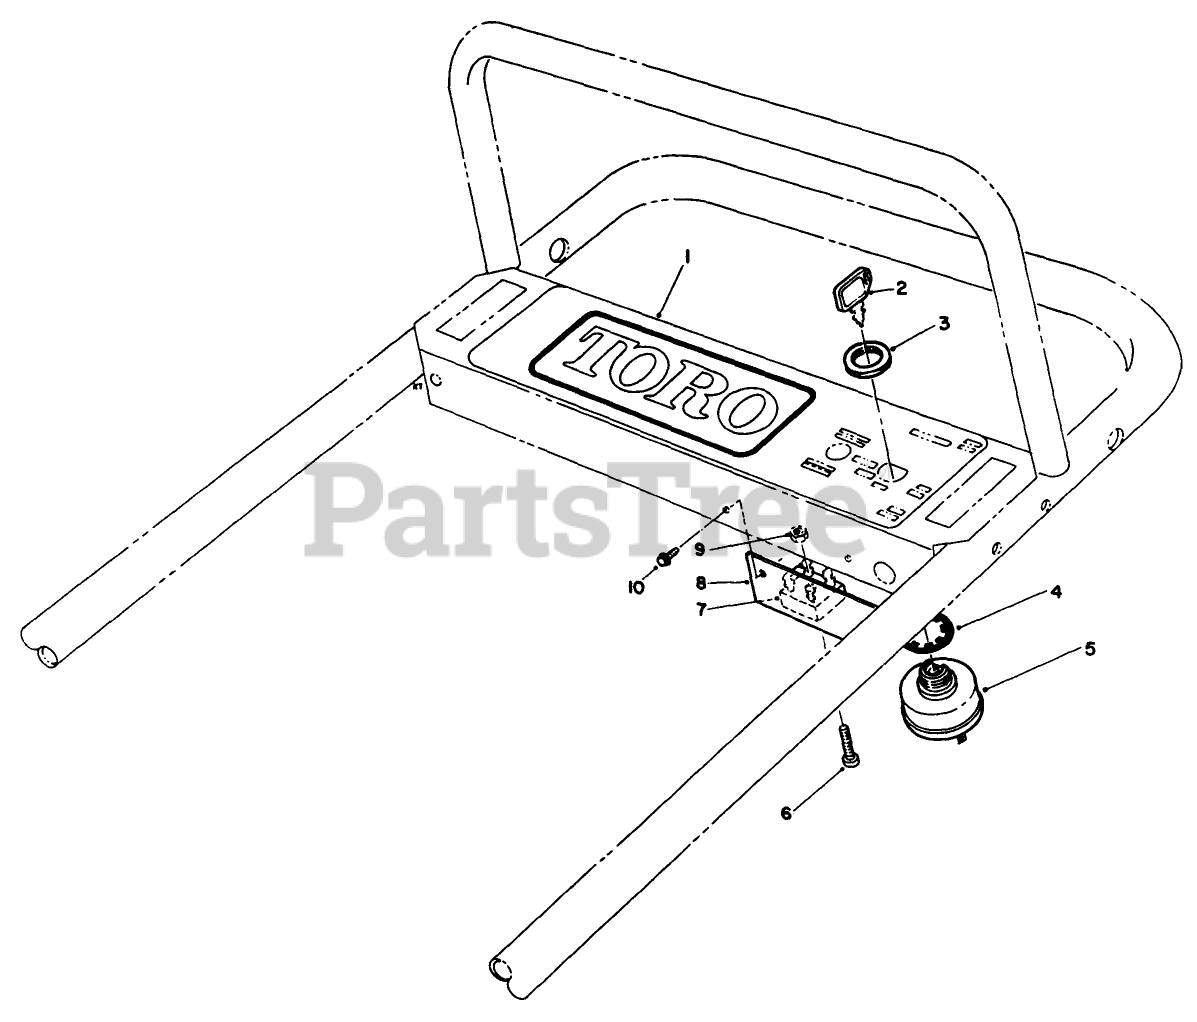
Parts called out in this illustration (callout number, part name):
1	Decal-Electric Start Panel
2	KEY-IGNITION
3	NUT-HH
4	WASHER-TOOTH, INTERNAL
5	Ignition Switch (Incl. Ref. #2-4)
6	SCREW-HWH
7	RECTIFIER-BRIDGE
8	PANEL-BOTTOM
9	NUT-LOCK, NI
10	SCREW-HWHTF
